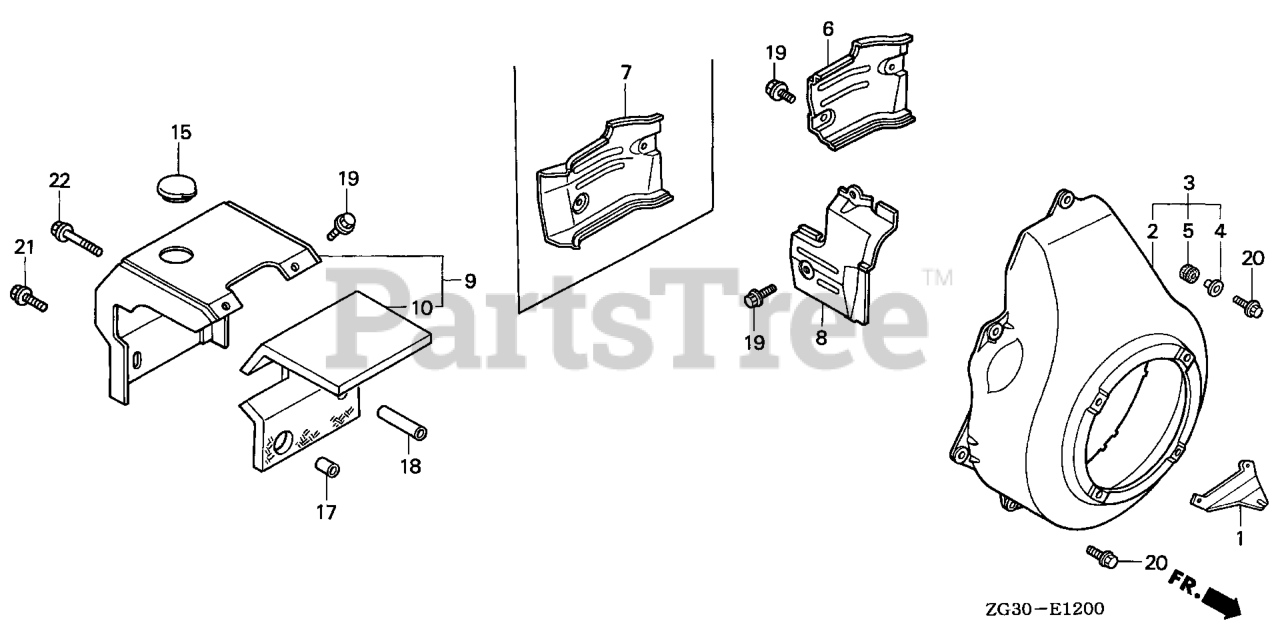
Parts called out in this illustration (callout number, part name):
2	COVER, FAN *NH116M* (URBAN SILVER METALLIC)
6	SHROUD (A)
8	SHROUD (B)
19	BOLT, FLANGE (6X12) Use up to Engine SN 1543277.
20	BOLT, FLANGE (6X12) Use up to Engine SN 1543277.
